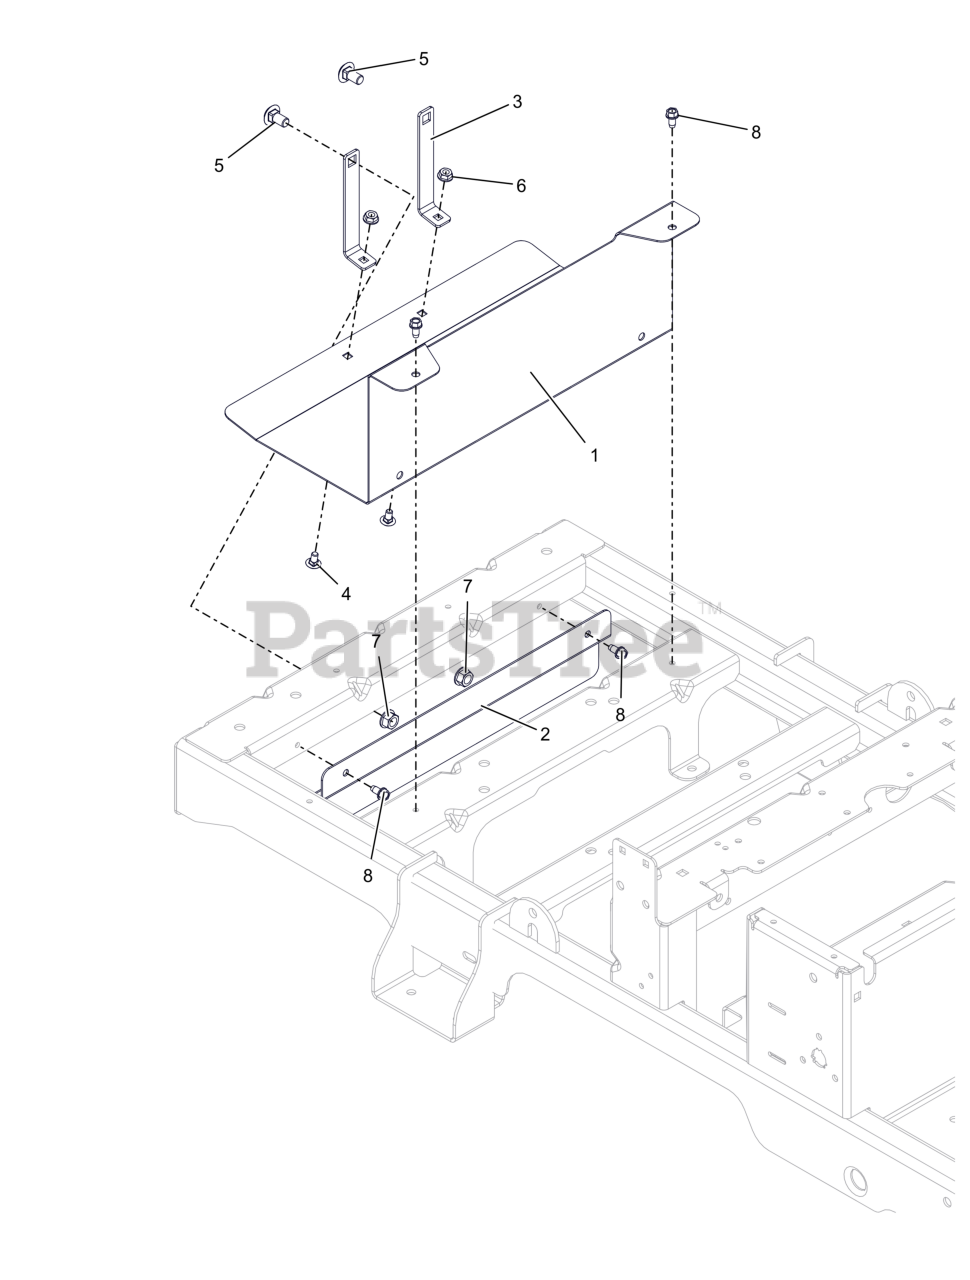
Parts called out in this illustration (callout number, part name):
1	GUARD, HEAT SHIELD (ZOOM/ZT)
2	GUARD, EXHAUST (BLACK)
3	STRAP, HEAT SHIELD (ZOOM/ZT)
4	BLT, RHSN .25-20X.500 G5 ZCC
5	BLT, RHSN .38-16X.750 G5 ZCC
6	NUT-LK-CTR-FLG .25-20 ZC120
7	NUT-LK-CTR-FLG .375-16 GF ZCC
8	SCR-TAP .25-20X.50 HWH ZCC
